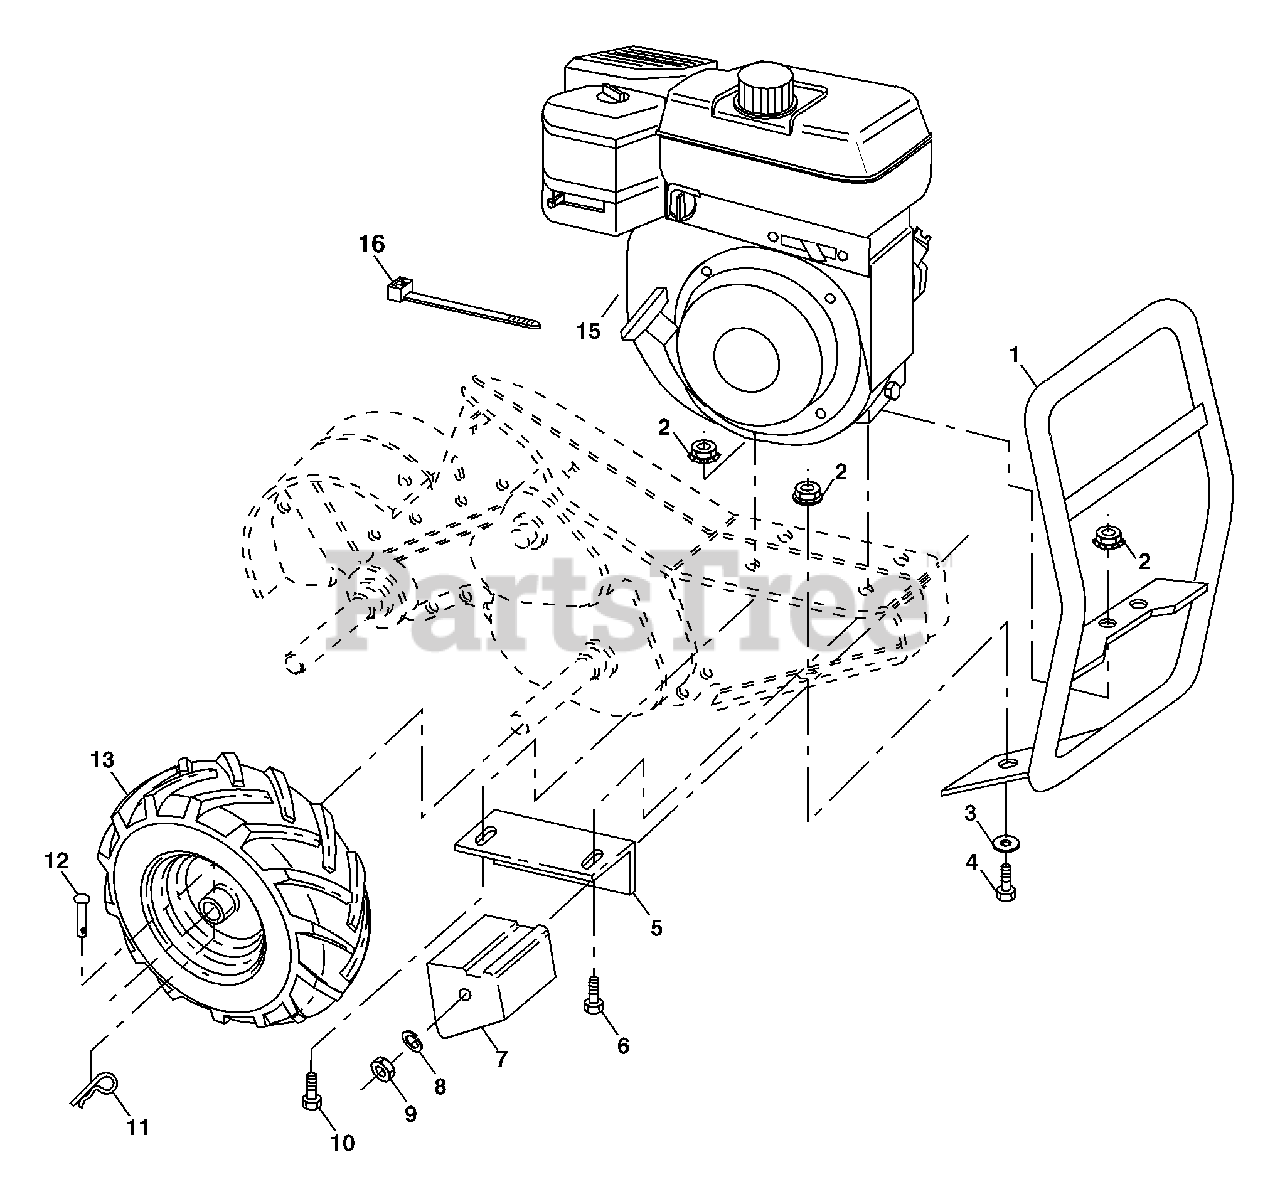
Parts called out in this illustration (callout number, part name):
1	Bumper
2	Locknut, Hex, Flange 5/16-18
3	Washer 11/32 x 11/16 x 16 Ga.
4	Bolt, Hex 5/16-18 x 3/4
5	Bracket, Reinforcement
6	Bolt, Hex 5/16-18 x 2
7	Counter Weight, R.H.
8	Washer, Lock 3/8
9	Nut, Hex 3/8-16
10	Bolt, Hex 5/16-18 x 1-1/2
11	Clip, Hairpin
12	Rivet, Drilled
13	Tire
13	Rim
13	Tire Valve
16	Tie Cable
